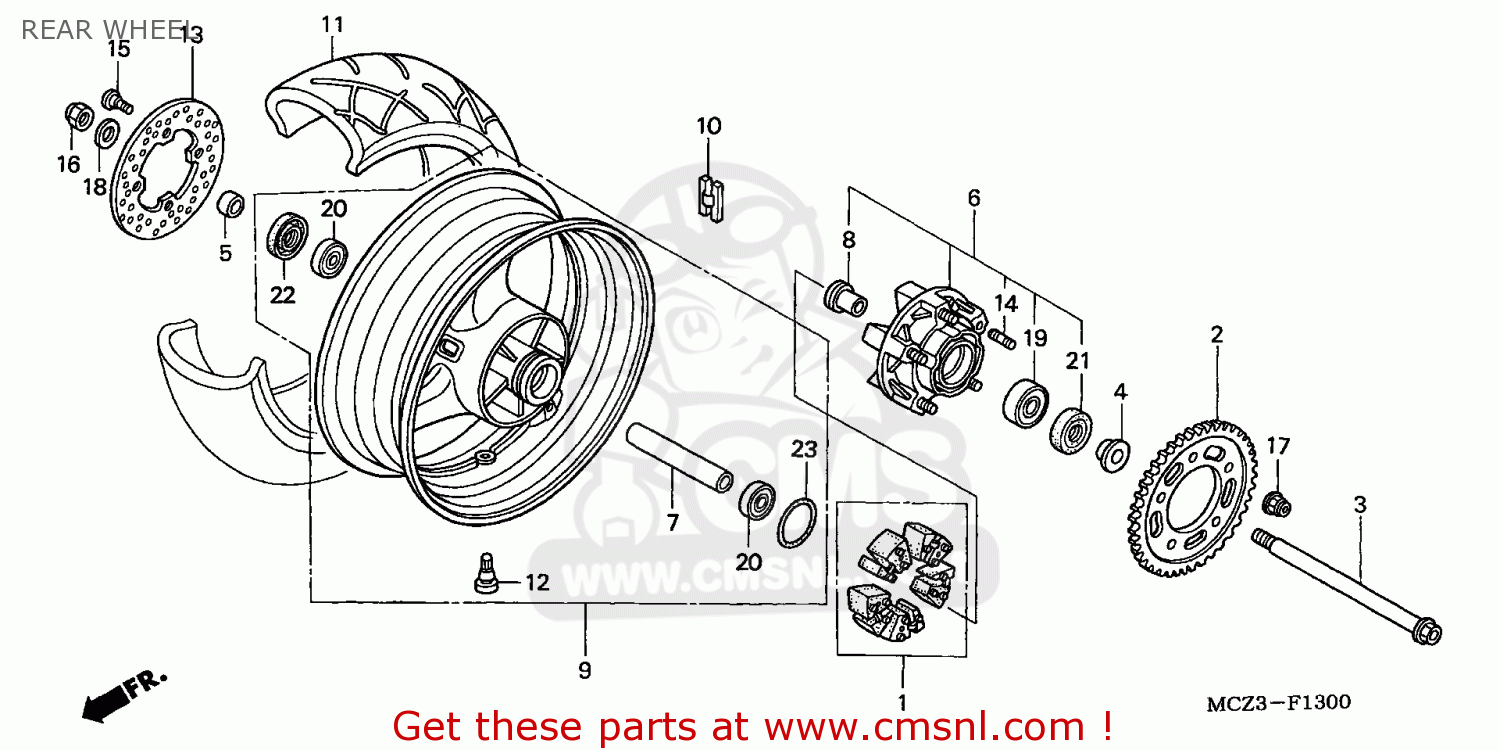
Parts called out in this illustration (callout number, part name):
1	DAMPER SET,WHEEL
2	SPROCKET,FINAL DR
3	AXLE,RR WHEEL
4	COLLAR L,RR WHEEL
5	COLLAR,REAR BRAKE
6	FLANGE SUB ASSY,R
7	COLLAR,RR AXLE DI
8	COLLAR B,RR WHEEL
9	WHEEL SUB ASSY,RR
10	WEIGHT,BAL.20G
11	TIRE,RR
12	VALVE,RIM (BS)
13	DISK,RR BRAKE
14	BOLT,STUD 2,12X25
15	BOLT,ENG HANG B
16	NUT,U,18MM
17	NUT,FLANGE 12MM
18	WASHER,20X31.5X2
19	BEARING,BALL,RADI
20	BEARING,BALL RADI
21	DUST SEAL,30X56X7.5
22	DUST SEAL,30X47X7
23	O-RING,61X2
